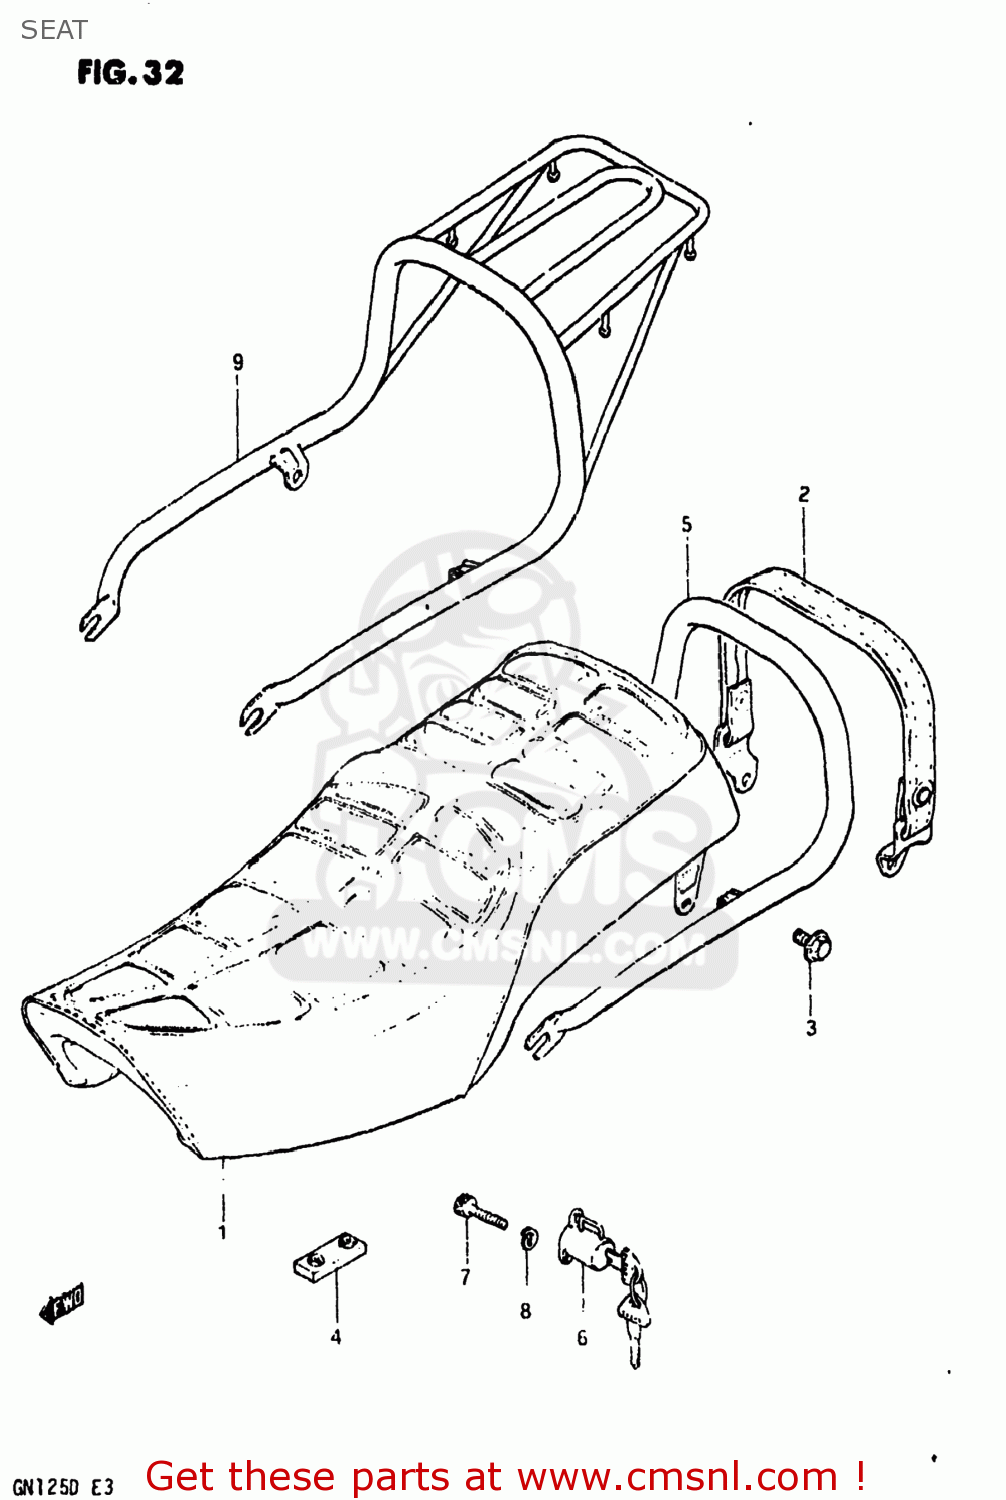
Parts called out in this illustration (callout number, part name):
1	SEAT ASSEMBLY
2	BAND,SEAT
3	BOLT, LOWER
4	CUSHION
5	HANDLE,PILLION RIDER
6	LOCK SET,HELMET
7	BOLT 6X11
8	LOCK WASHER
9	CARRIER
